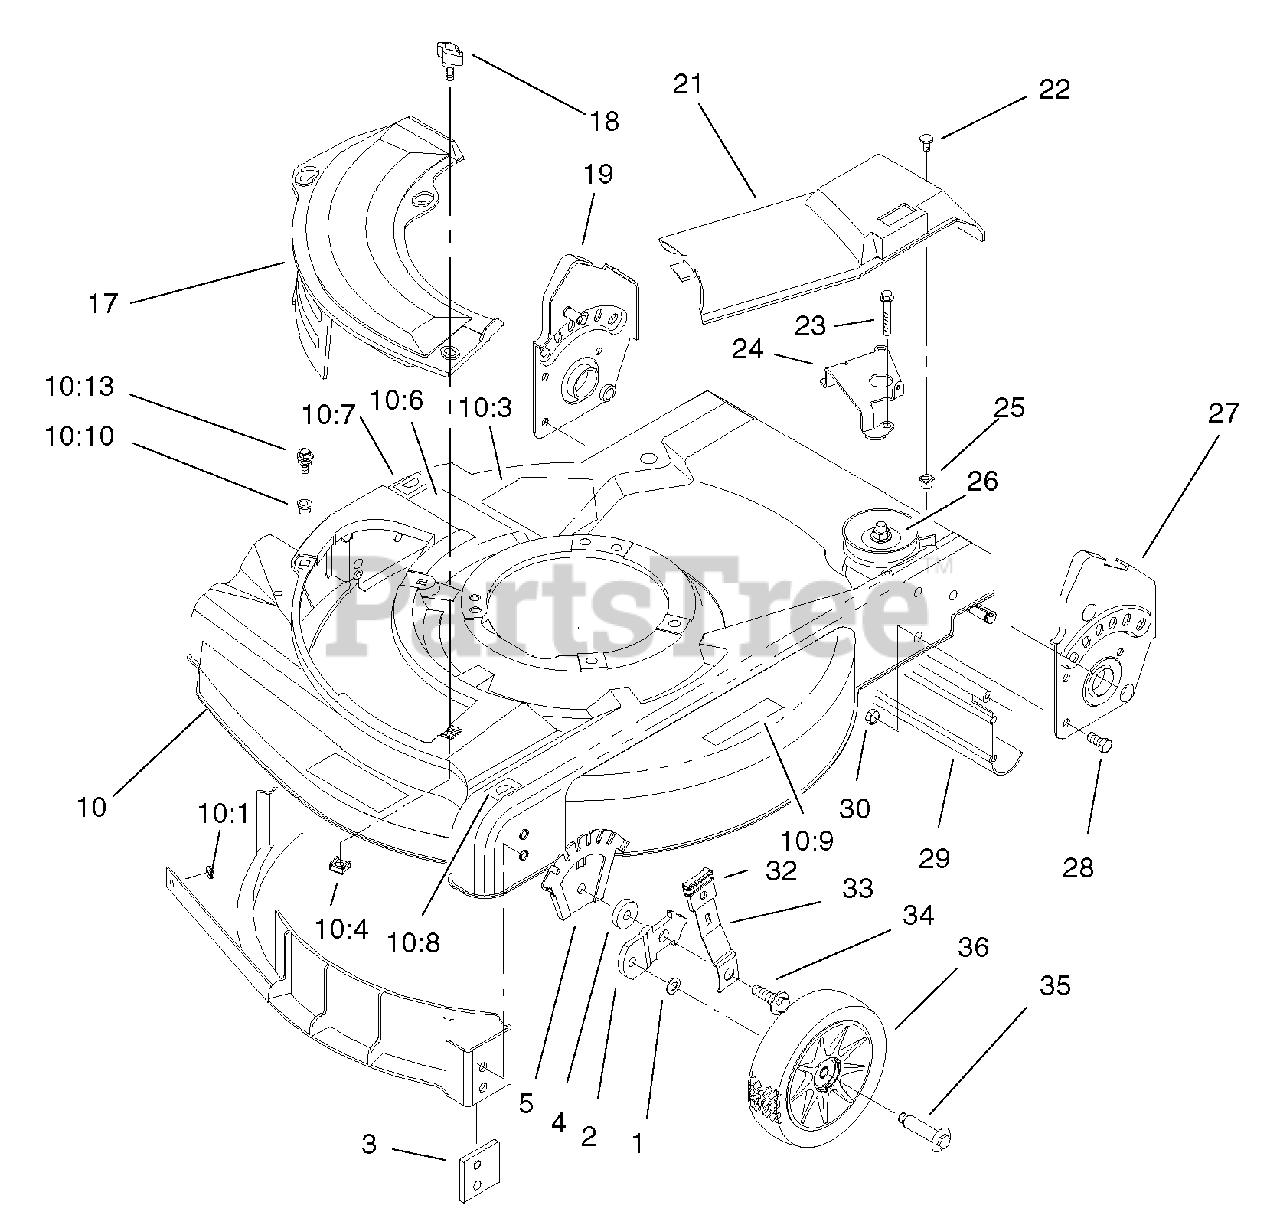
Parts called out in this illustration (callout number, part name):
2	Bracket-Height Adjustment, Wheel
3	Plate-Baffle
4	Washer-Wheel
5	Plate-Height, Adjustment
10	Housing (only on: 10360c)
10	Deck ASM (only on: 10360)
10:1	Washer-Flat
10:3	Decal-Danger (only on: 10360)
10:3	Danger Decal (only on: 10360c)
10:4	Nut-Cage
10:6	Decal-Warning (only on: 10360c)
10:6	Decal-Warning (only on: 10360)
10:7	Decal-HOC, RH (only on: 10360)
10:7	Decal-HOC,RH (only on: 10360c)
10:8	Decal-HOC, LH (only on: 10360)
10:8	Decal-HOC,LH (only on: 10360c)
10:9	Decal-Warning (only on: 10360)
10:9	Decal-Warning (only on: 10360c)
10:10	Grommet-Plastic
10:13	Screw-Sems
17	Plate-Mulch
19	RH Bracket ASM
21	Cover-Drive
23	Screw-HWHTF
24	Guide-Transmission
25	Grommet
26	Gear Case ASM
27	LH Bracket ASM
28	Screw-HH
29	Shield-Trailing
30	Nut-Lock, NI
32	Knob-Lever, Height Adjustment
33	Arm-Front Spring
34	Bolt-Shoulder
35	Bolt-Shoulder
36	Wheel & Tire ASM
